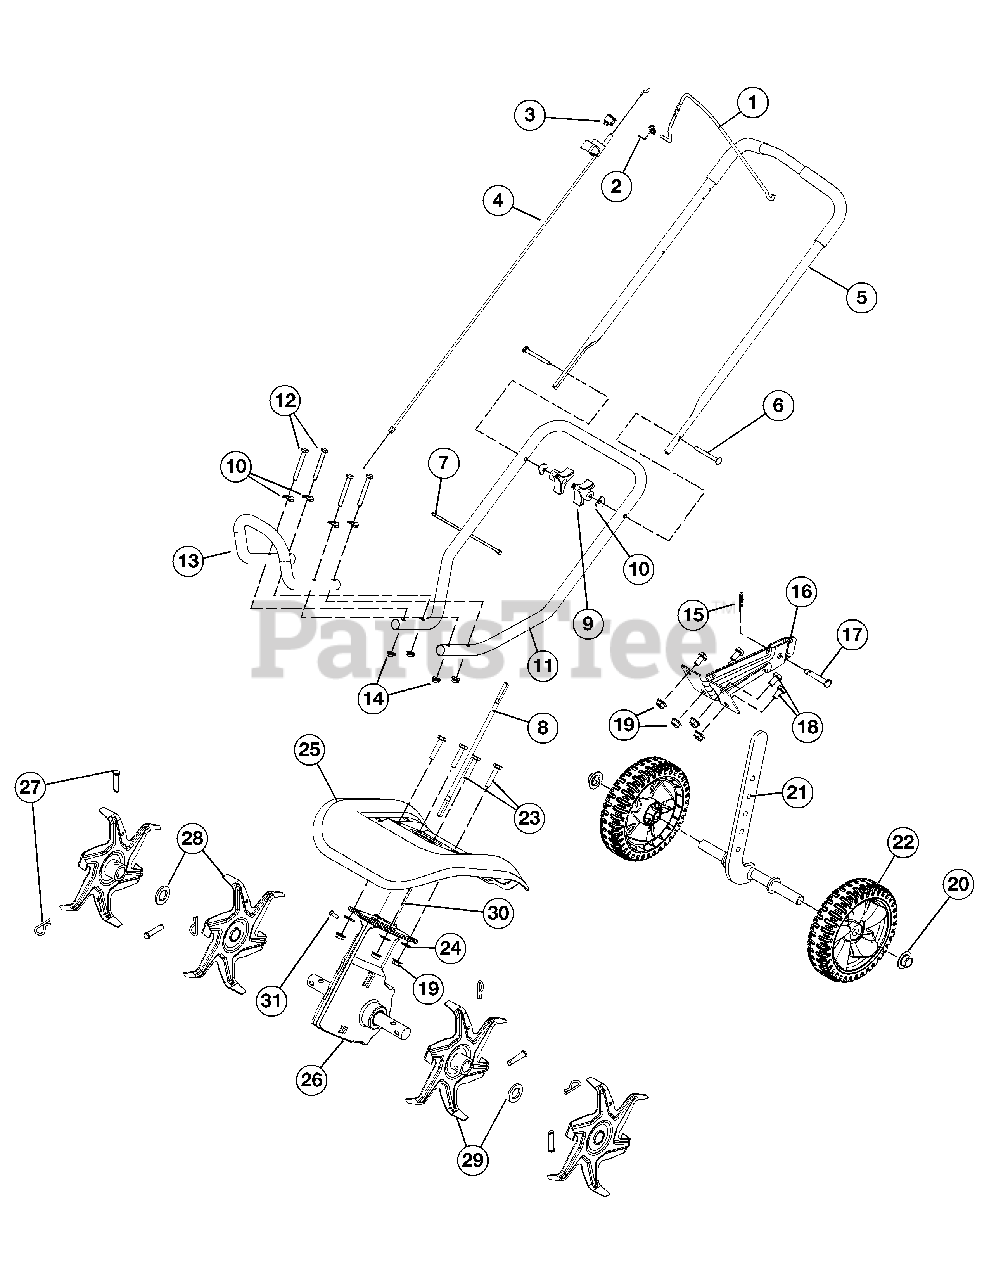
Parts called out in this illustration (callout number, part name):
1	Throttle Control
2	Torsion Spring (includes 7)
3	On/Off Switch
4	Throttle Cable
5	Upper Handle
7	Cable Tie
8	Flex Shaft
10	Shoulder Washer
11	Lower Handle
12	Screw
13	Front Handle
14	Lock Nut
15	Cotter Pin
16	Tailpiece Bracket Assembly
17	Clevis Pin
18	Cap Screw
19	Lock Nut
20	Cap Push
21	Wheel Support Bracket Assembly
22	Wheel
23	Cap Screw
24	Washer
25	Tine Shield
26	Gear Box Assembly
27	Tine Fastener Assembly
28	Tine Assembly (Left Outer or Right Inner)
29	Tine Assembly (Left Inner or Right Outer)
30	Drive Shaft Housing
31	Anti Rotation Screw
